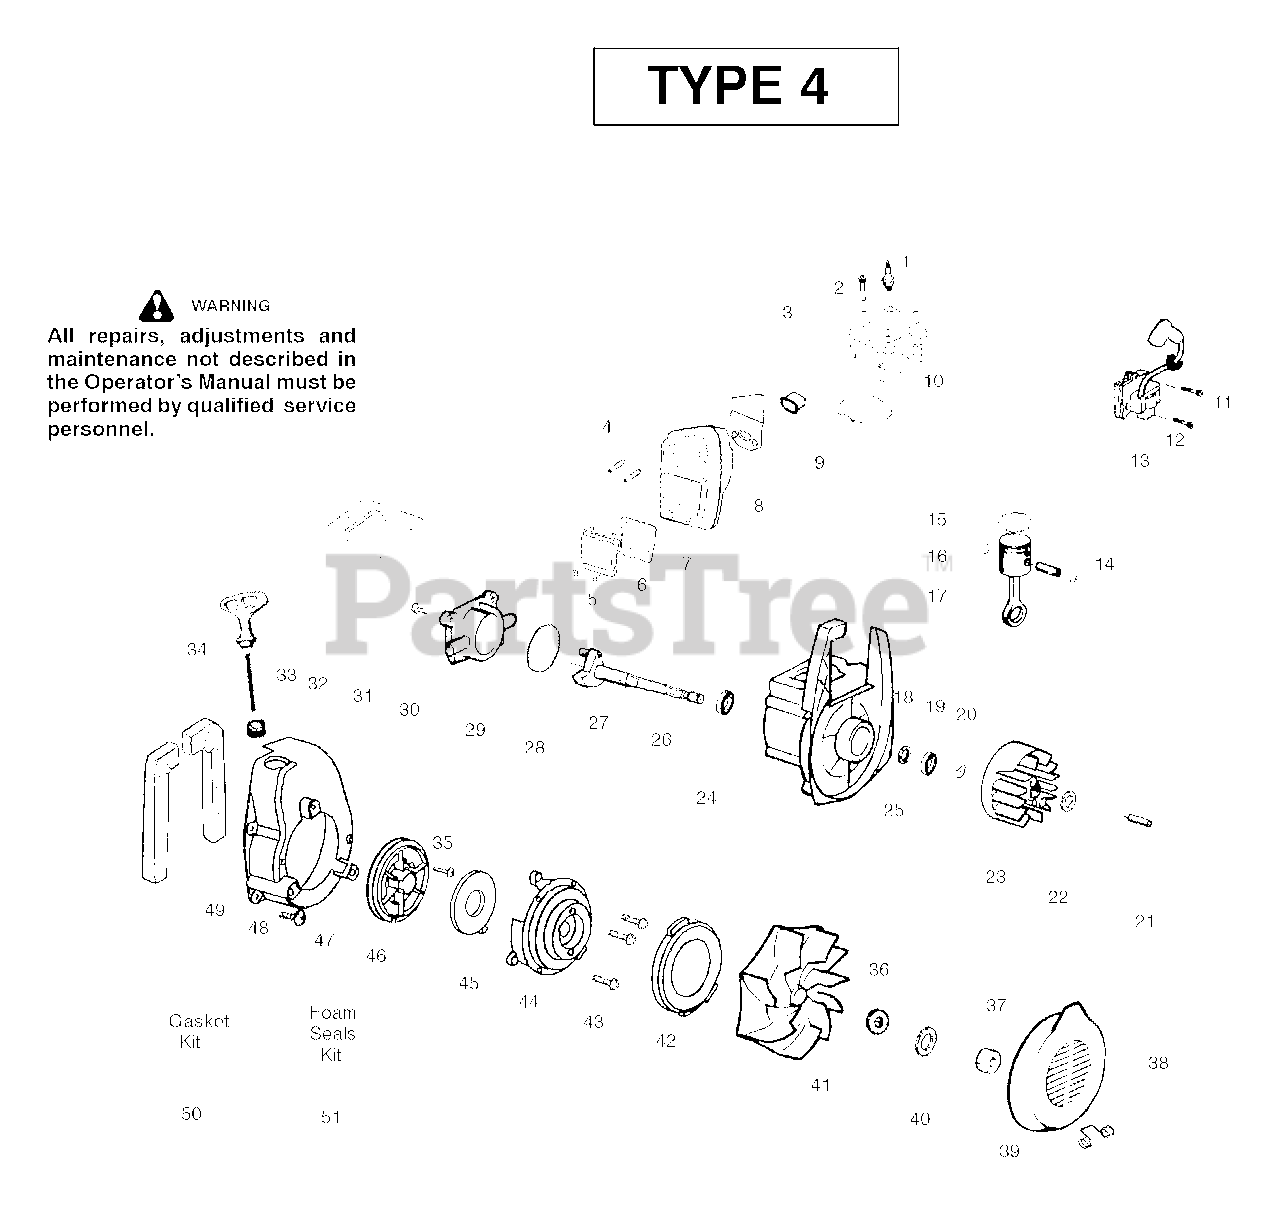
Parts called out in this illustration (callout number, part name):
1	Spark Plug (RCJ-6Y)
3	Insulator-Heat
4	Screw-Muffler-Internal
6	Kit-Spark Screen
7	Kit-Muffler
8	Gasket-Baffle (kit)
9	Gasket-Cylinder (kit)
10	Kit-Cylinder
11	Grommet-Ign. Module
12	Screw-Ignition Module
13	Ignition Module
14	Kit-Piston
15	Piston Ring
16	Retainer-Piston Pin
17	Assy-Connecting Rod
18	Seal-Crankcase
19	Bearing-Outer
20	Retainer Ring-C'chaft
21	Spacer-Flywheel
23	Assy-Flywheel
24	Assy-Crankcase/Crankshaft
25	Assy-Crankcase
26	Bearing-Inner
27	Assy-Crankshaft
28	O-ring-C/case (kit)
29	Cover-Crankcase
30	Screw
31	Foam-219mm (kit)
32	Eyelet-Flange
33	Kit-Rope
34	Handle-Starter
35	Screw-Rope
36	Washer-Belleville
38	Spring-Return Cover
39	Inlet Door
41	Assy-Impeller
42	Seal-Ring
44	Housing-Pulley
45	Spring-Starter
46	Kit-Starter Pulley
47	Fan Housing
48	Screw
49	Foam-182mm (kit)
50	Kit-Gasket
51	Kit-Foam Seals
